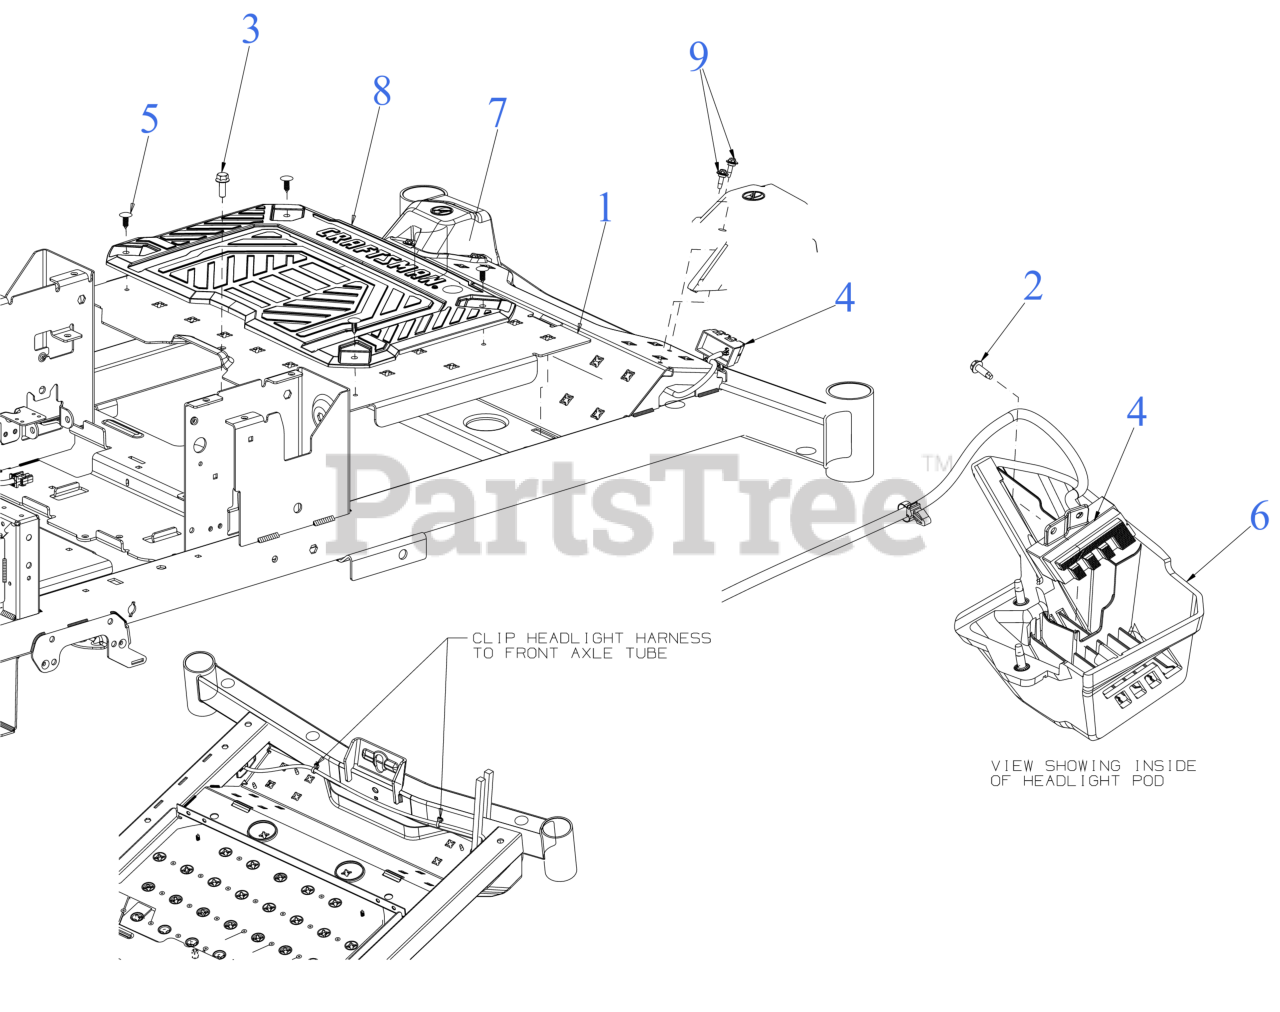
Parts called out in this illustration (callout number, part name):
1	FLOORBOARD
2	SCREW #8-16 x .50
3	SCREW 5/16-18 x .875 GR5 HXFLG HD
4	HEADLIGHT HARNESS
5	RATCHET CLIP .250
6	HEADLIGHT COVER (RH)
7	HEADLIGHT COVER (LH)
8	FLOORBOARD MAT
9	SHOULDER SCREW M6-1 .368 X.115
